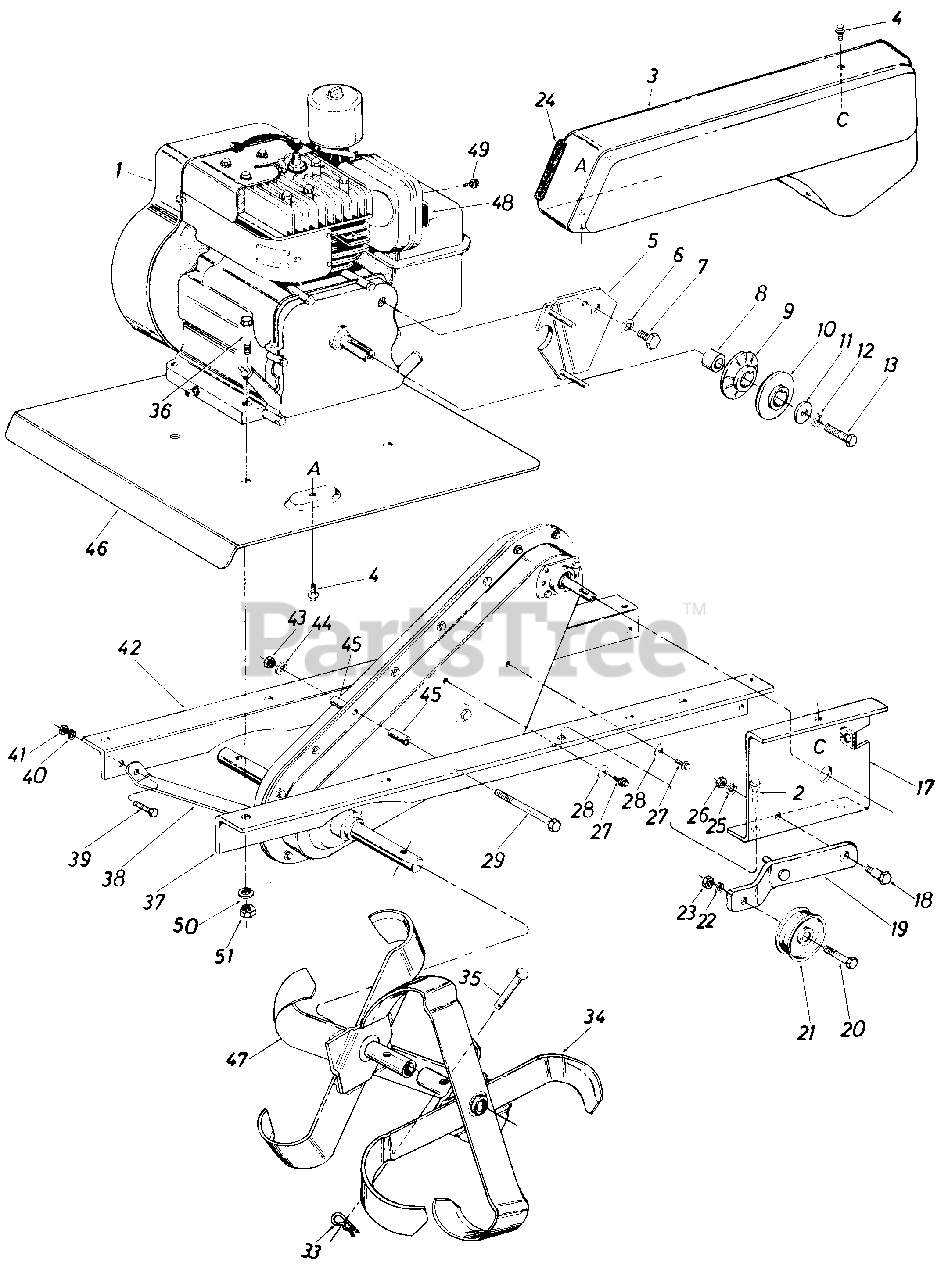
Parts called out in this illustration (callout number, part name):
1	Engine
2	Hex Wash. Hd. Se I f-Tap Scr. 5/16-24 x .50" Lg.
3	Belt Cover
4	Hex Wash. Hd. Self-Tap Scr. 1/4-20 x .50" Lg.
5	Belt Keeper Brk't. Ass'y.
6	Internal L-Wash. 1/2" I.D.
7	Hex Scr. 1/2-20 Thd.
8	Spacer
9	Pulley Half
10	Pulley Half
11	Fl-Wash. 3/8 I.D. x 1.25" O.D. x .100
12	L-Wash. 3/8 I.D.
13	Hex Scr. 3/8-24 x 1.00" Lg.
17	Idler Mounting Brk't.
18	Shld. Bolt
19	Id ler Bracket Ass'y.
20	Hex Scr. 3/8-16 x 1.50" Lg.
21	Idler Pulley
22	L-Wash. 3/8 I.D.
23	Hex Jam Nut 3/8-16 Thd.
24	Trim Strip 3"
25	L-Wash. 3/8 I.D.
26	Hex Jam Nut 3/8-16 Thd.
27	Hex Wash. Hd. Self-Tap Scr. 1/4-20 x .50" Lg.
28	Belleville Wash. .26 I.D. x .75 O.D. x .060
29	Hex Scr. 5/16-18 x 2.75" Lg.*
33	Hairpin Cotter
34	See Tine Chart
35	Clevis Pin
36	Hex Bolt 5/16-18 x 1.5" Lg.*
37	Frame Rail L.H.
38	Front Brace Brk't.
39	Hex Scr. 5/16-18 x .75" Lg.*
40	L-Wash. 5/16" I.D.*
41	Hex Cent. L-Nut 5/16-18 Thd.
42	Frame Rail R.H.
43	Hex Cent. L-Nut 5/16-18 Thd.
44	L-Wash. 5/16" I.D.*
45	Spacer
46	Tine Shield
47	See Tine Chart
48	Deflector
49	Hex Self-Tap Scr. #8-32 x .38" Lg.
50	L-Wash. 5/16" I.D.*
51	Hex Nut 5/16-18 Thd.*
